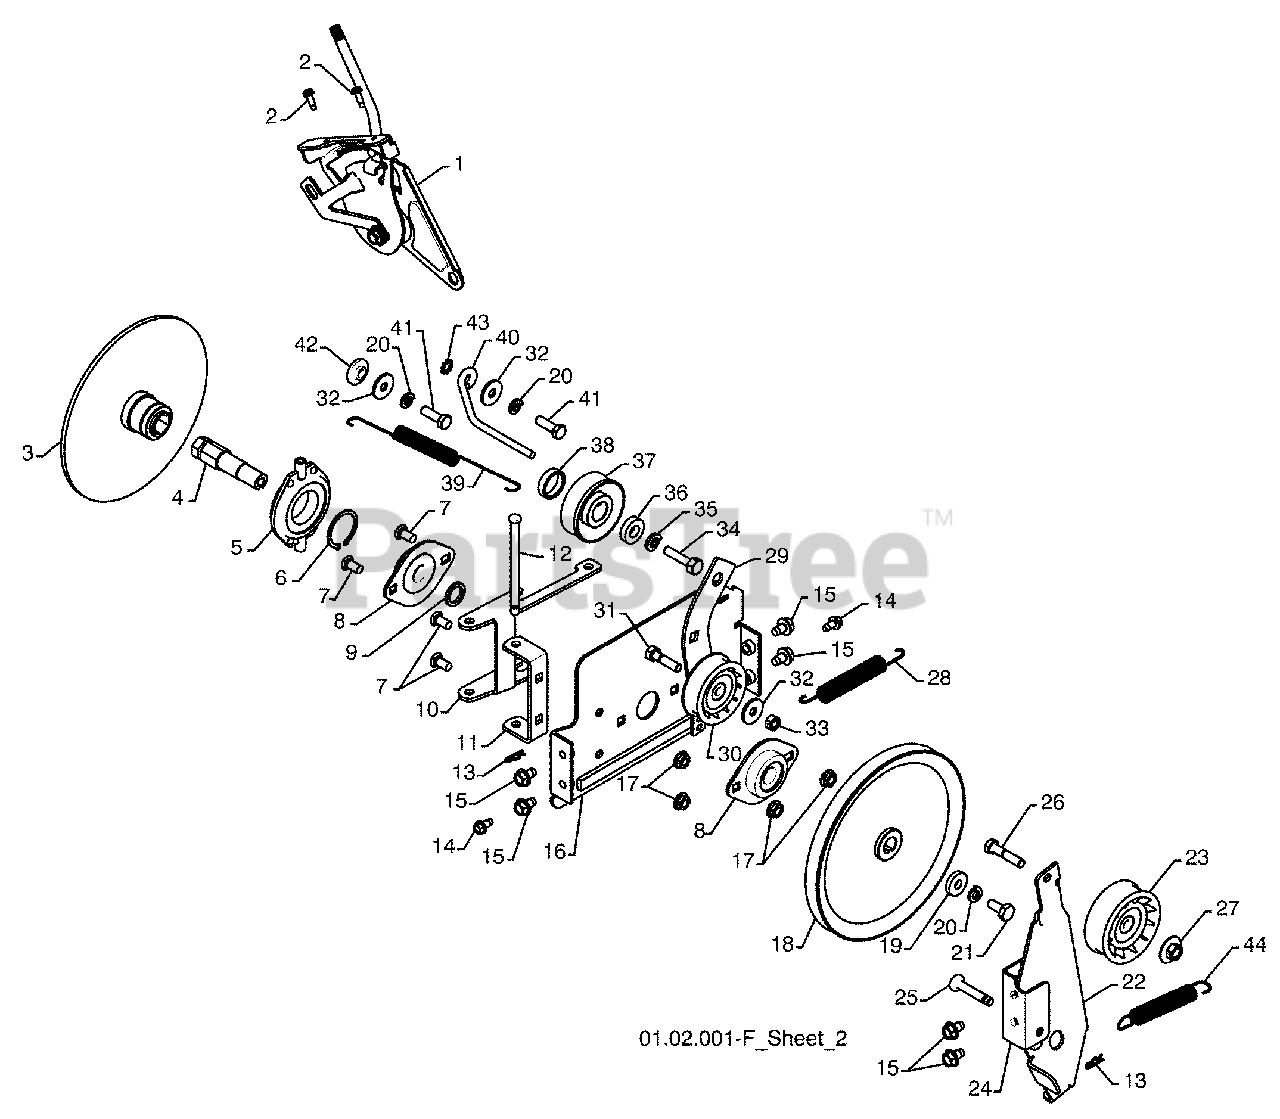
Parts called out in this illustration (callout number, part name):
1	SPEED SELECTOR HEAD ASSEMBLY
2	SCREW 10-24 X .625
3	DRIVE PLATE WELDMENT
4	HEX SHAFT
5	TRUNNION BEARING ASSEMBLY
6	RETAINER
7	CARRIAGE BOLT 5/16-18 X .625
8	FLANGE BEARING
9	SPACER
10	LEVER SHIFTER PLATE
11	SHIFTER SUPPORT BRACKET
12	PIN
13	RETAINER
14	SCREW 1/4-20 X .500
15	BOLT 5/16-18 X .500
16	DRIVE MOUNT PLATE
17	NUT 5/16-18
18	TRACTION PULLEY
19	WASHER
20	LOCKWASHER 5/16
21	SCREW 5/16-18 X .750
22	IDLER BRAKE ARM
23	IDLER PULLEY
24	IDLER PIVOT BRACKET
25	PIN
26	SCREW 5/16-18 X 1.50
27	NUT 5/16-18
28	TRACTION SPRING
29	IDLER TRACTION ARM
30	IDLER PULLEY
31	SCREW 5/16-18 X 1.25
32	WASHER
33	NUT 5/16-18
34	SCREW 3/8-24 X 1.38
35	LOCKWASHER 3/8
36	WASHER
37	ENGINE TRACTION PULLEY
38	SPACER
39	RETURN SPRING
40	BELT GUIDE
41	SCREW 5/16-18 X 1.00
42	BUSHING
43	LOCKWASHER 5/16
44	BRAKE SPRING
